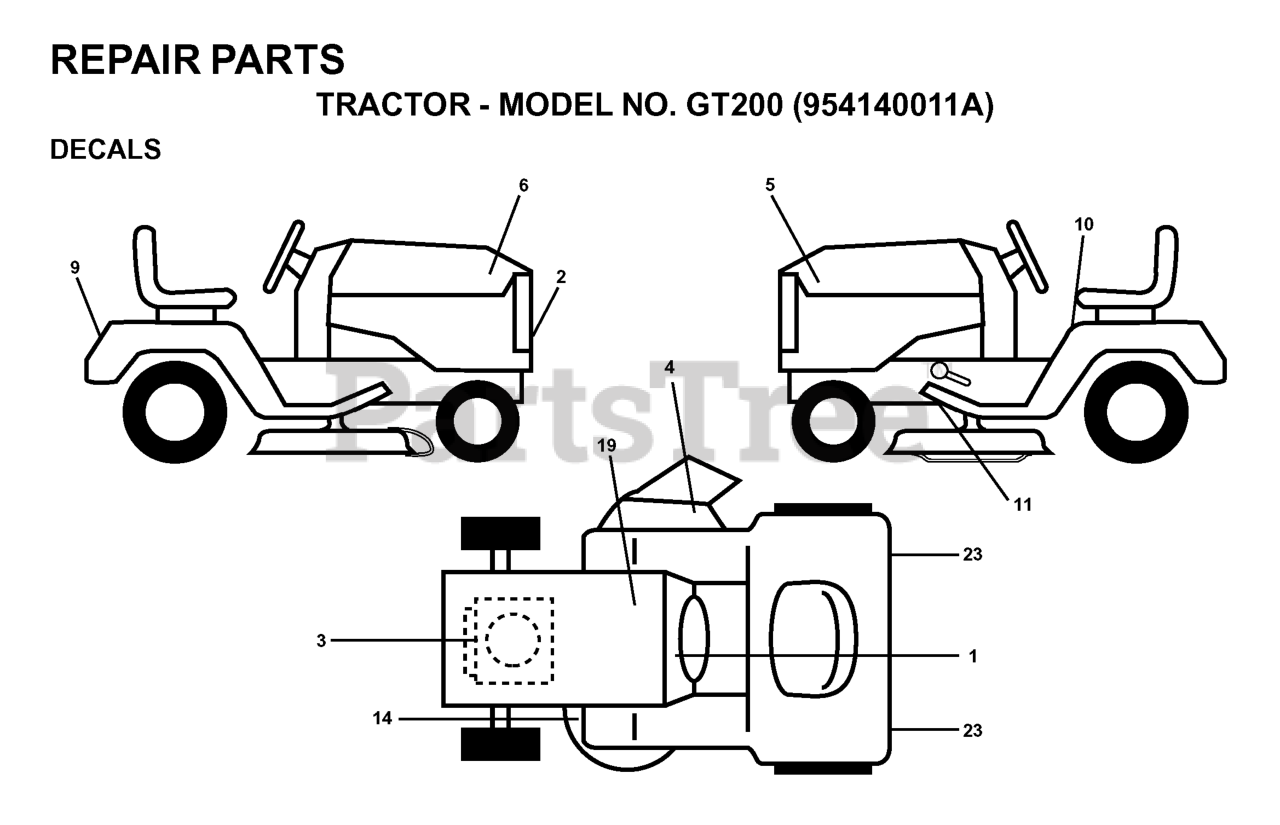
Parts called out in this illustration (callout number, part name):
2	DECAL.GRILLE.HUSQ
4	DECAL WARNING (ENGLISH/FRENCH)
5	DECAL HOOD LH GT200
6	DECAL HOOD RH GT200
9	DECAL FENDER HUSQ
10	DECAL FENDER DANGER
19	DECAL, BATTERY DANGER
23	REFLECTOR-TAIL YT
